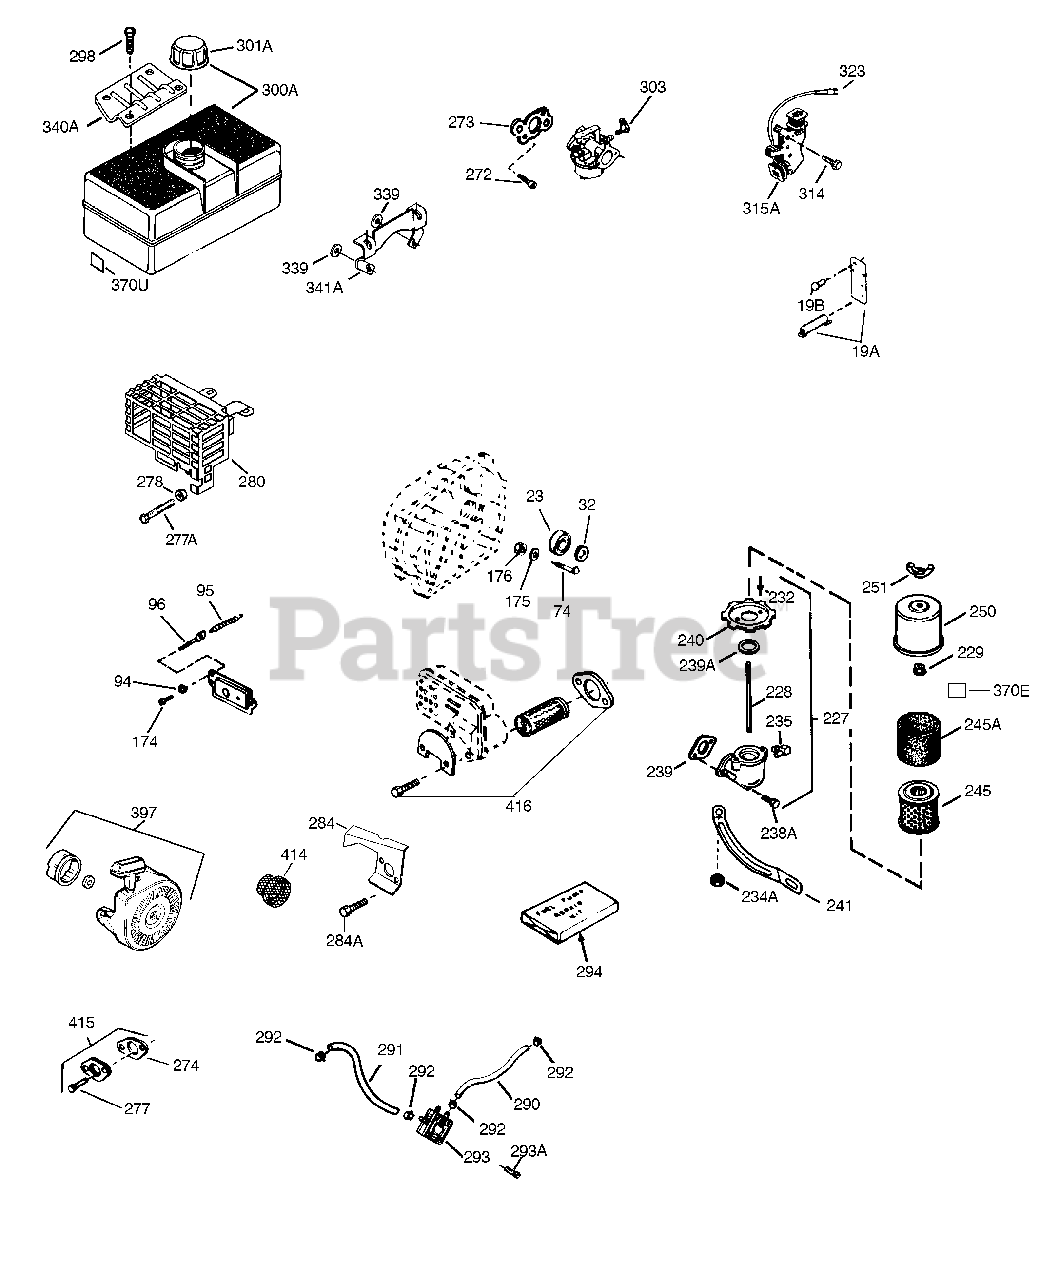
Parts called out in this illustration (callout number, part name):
124	Screw, 1/4-20 x 9/16"
161	Screw, T-30, 1/4-20 x 1/2"
174	Screw, 10-24 x 1/2"
186	Governor Link
238	Screw, 10-32 x 1/2"
239	* Air Cleaner Gasket
240	Air Cleaner Body
245	Air Filter (Paper) also available in Packaged Part #740027B
245A	Poly Pre-Filter (also available in Pa ckaged Part #740027B)
250	Air Cleaner Cover
251	Wing Nut, 1/4-20
277	Screw, 5/16-18 x 3-3/16"
277A	Screw, 5/16-18 x 3-31/32"
280	Heat Shield
291	Fuel Line
292	Fuel Line Clamp
298	Screw, 1/4-15 x 3/4"
340A	Fuel Tank Bracket
341A	Fuel Tank Bracket
416	Spark Arrestor Kit (Optional)
